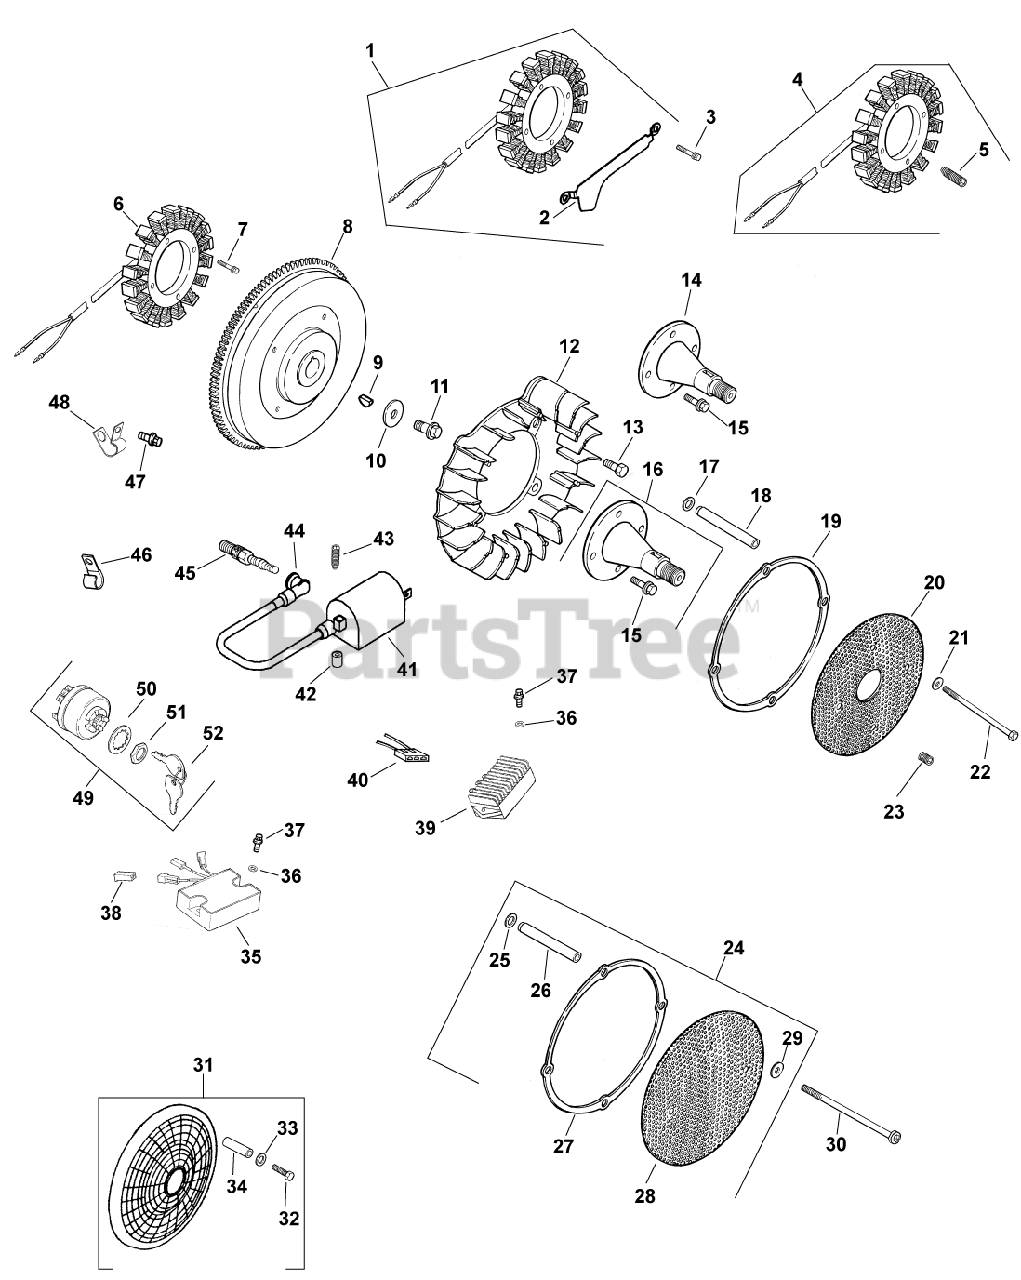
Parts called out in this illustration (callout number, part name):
6	STATOR - USE 28 085 02-S
7	SCREW, THD FROM M5X0.8X30
8	FLYWHEEL - (#2402530S)
9	KEY, 3/16" X 5/8"
10	WASHER, FLAT 13/32"
11	SCREW, FLG M10X1.5X45 - (#25086361S)
31	KIT, GRASS SCREEN
32	SCREW, SLT HD CAP M4X0.7X25
33	WASHER, FLAT 3/16"
34	SPACER - DISCONTINUED
35	KIT, FULL WAVE CONVERSION
36	WASHER, FLAT 3/16"
37	SCREW, PHL HD #11-16X7/8"
38	CONNECTOR
41	COIL, IGNITION
43	SCREW,WSH HD TAP 1/4-14X1 1/2"
44	BOOT, SPARK PLUG
45	PLUG, SPARK (PRO SERIES)
47	SCREW,FLG THD FRM M5X0.8X16-(#25086398S)
48	CLAMP, INSULATED
